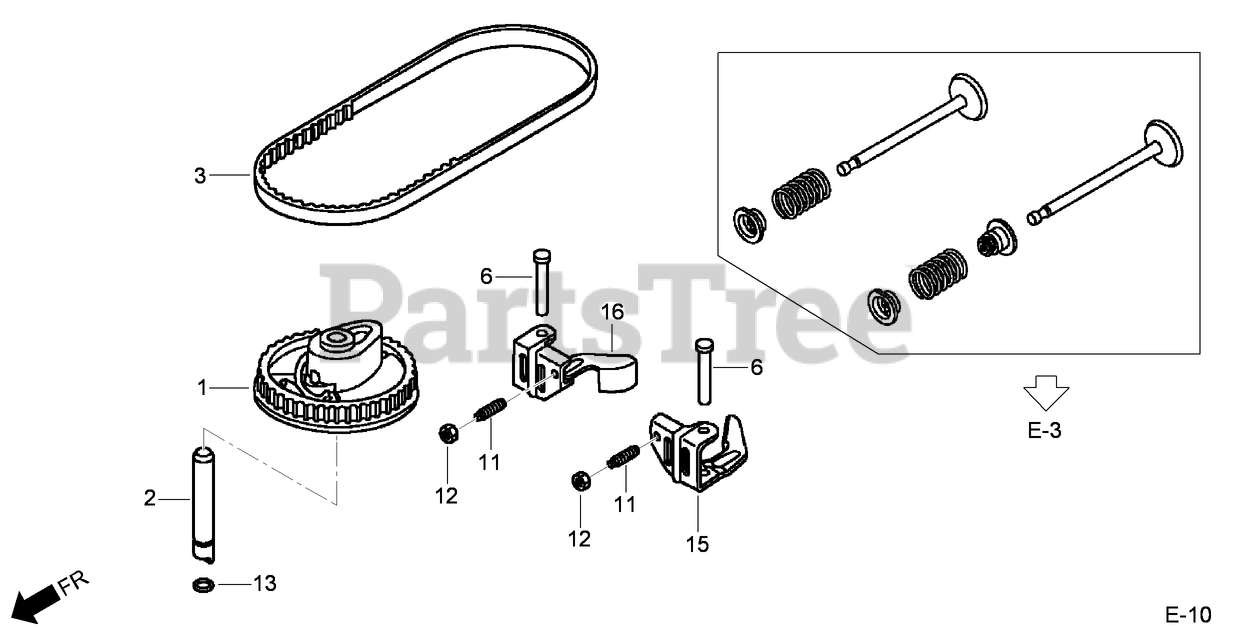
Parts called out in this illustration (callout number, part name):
1	PULLEY-CAMSHAFT
2	SHAFT-PULLEY, CAM
3	BELT-TIMING (84H U7 G-200)
6	SHAFT-ARM, ROCKER
11	SCREW-ADJUSTING, TAPPET
12	NUT-ADJUSTING, TAPPET
13	O-RING (6.8X19) (ARAI)
15	ARM-ROCKER, INTAKE VALVE
16	ARM-ROCKER, EXHAUST VALVE
